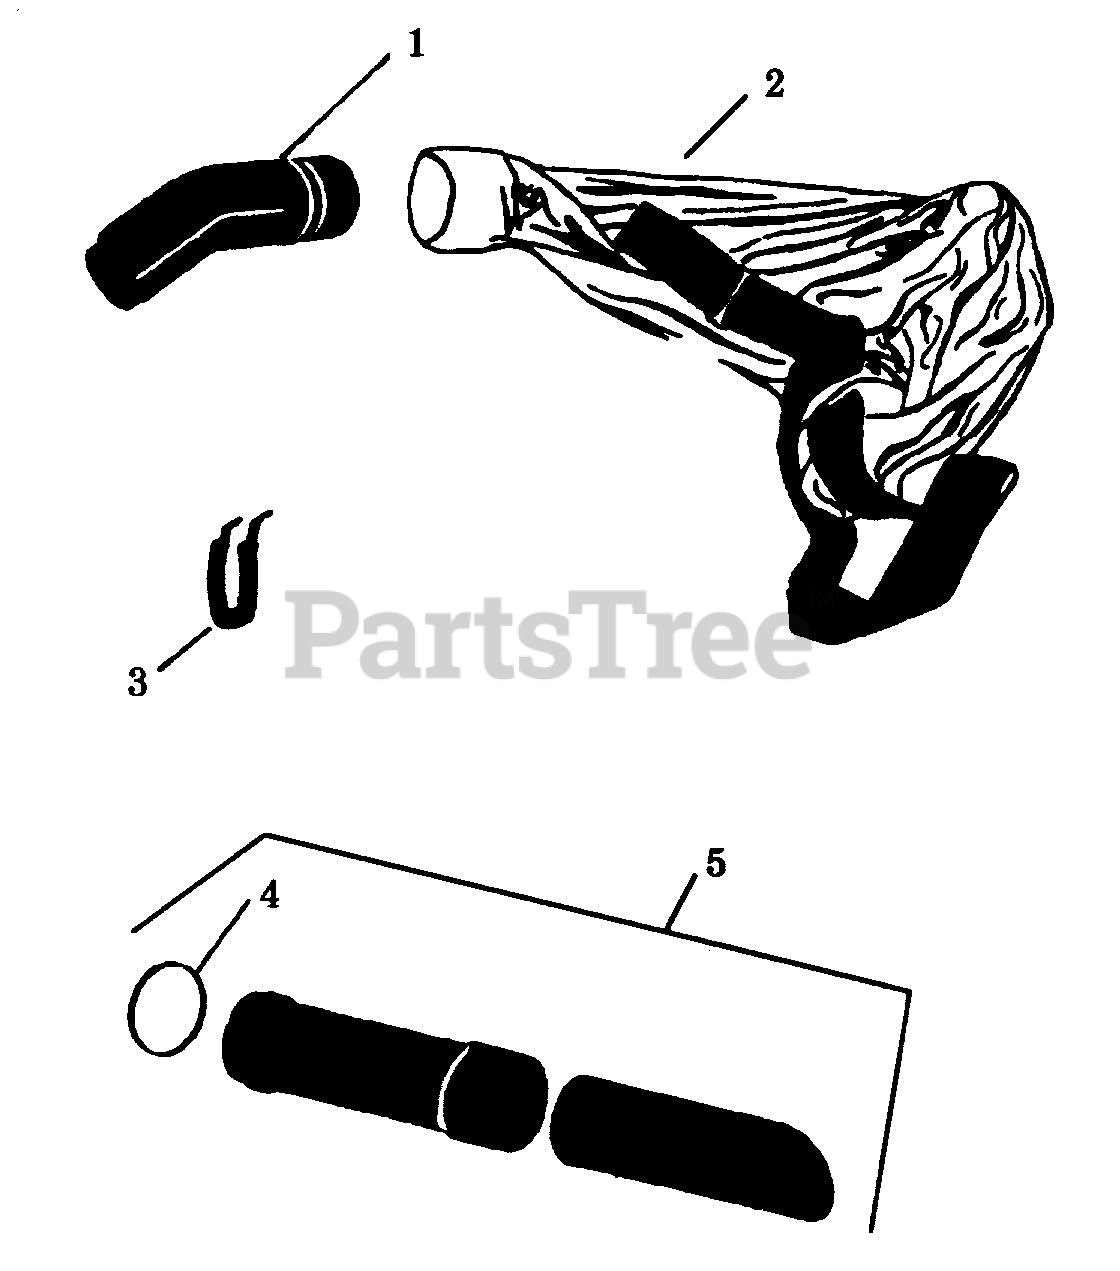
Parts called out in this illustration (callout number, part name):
2	Vacuum Bag Kit
3	Rear Handle Ass'y.
4	Spacer
5	Vacuum Tube Kit
